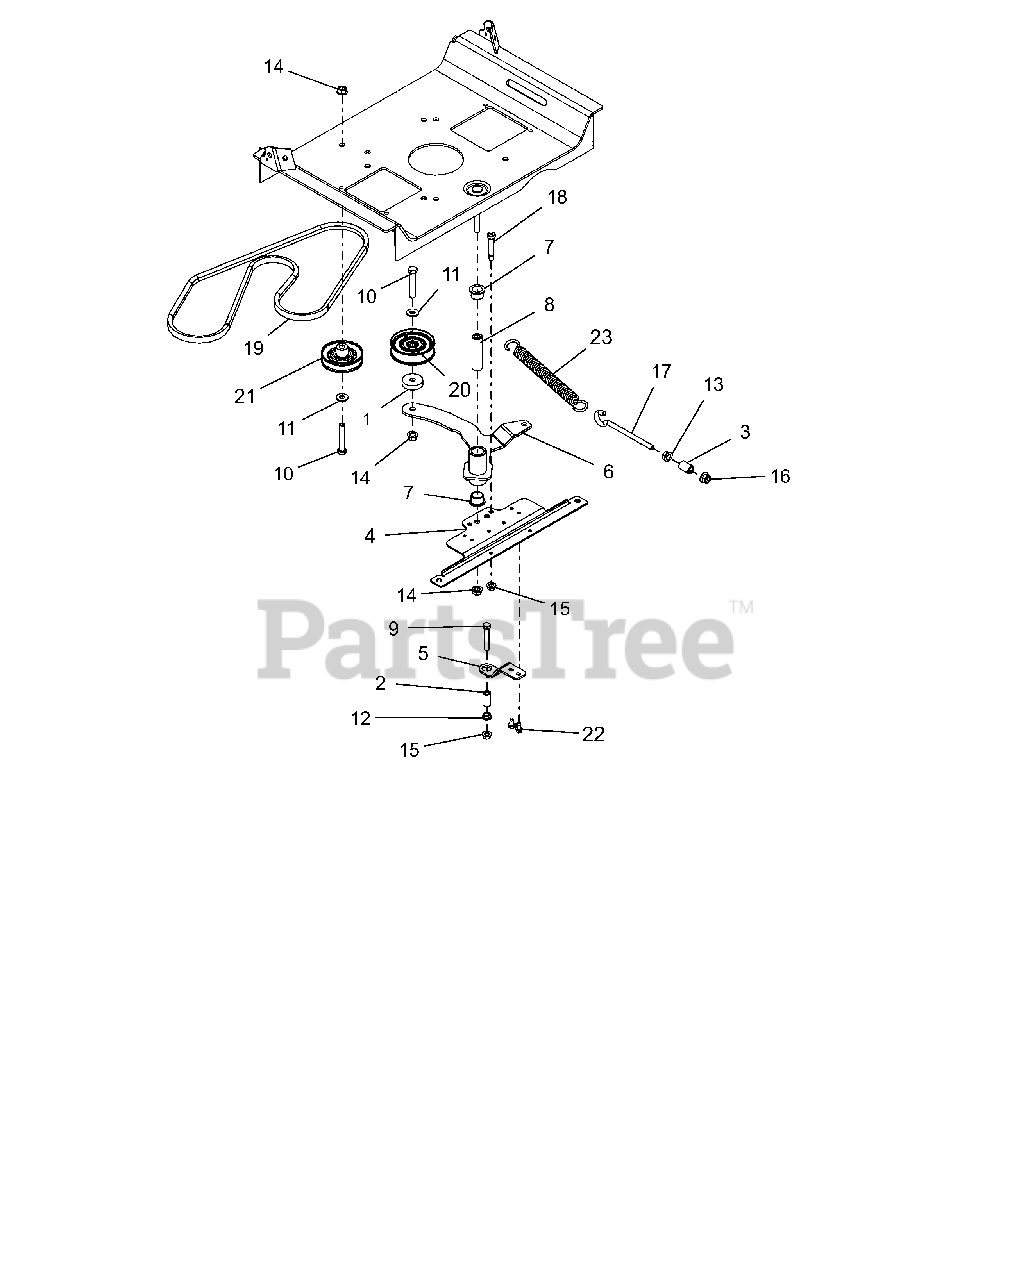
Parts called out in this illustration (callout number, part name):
1	SPACER, .39 X 1.50 X .380
2	SPACER, RUBBER 5/16 IDX1.0 LG
3	SPACER, .375X.625X.970 (PM)
4	BRKT, DRIVE IDLER MOUNTING
5	BRKT, CLUTCH STOP (XL)
6	WLDMT,GRD DRIVE IDLER ARM-LGR
7	BSHG-FLG 0.75X0.875X.625X1.125
8	BUSHING, SLEEVE .38X.750X2.78
9	@BLT-HEX .31-18X2.00 GR5 YWZC
10	@BLT-HEX .38-16X2.25 GR5 YWZC
11	@WSHR-FL-STL.38X.875X.083 YWZC
12	@NUT-SPNLK-FLG .312-18 YWZC
13	@NUT-SPNLK-FLG .375-16 YWZC
14	@NUT-LK-TOP-FLG .38-16 YWZC
15	@NUT-LK-TOP-FLG .31-18 YWZC
16	@NUT-LK-NYL-FLG .38-16 YWZC
17	BOLT,.38-16 X 4.25-.62 DIA EYE
18	BLT-SHLDR .38X1.5X.31-18 SLT Y
19	V-BELT, A-RAW EDGE
20	IDLER, FLAT - 3.05" X .75"
21	IDLER, V-3.000 OD
22	SCR-TAP .25-20X.50 HWH TR YWZ
23	SPRING, EXTENSION
